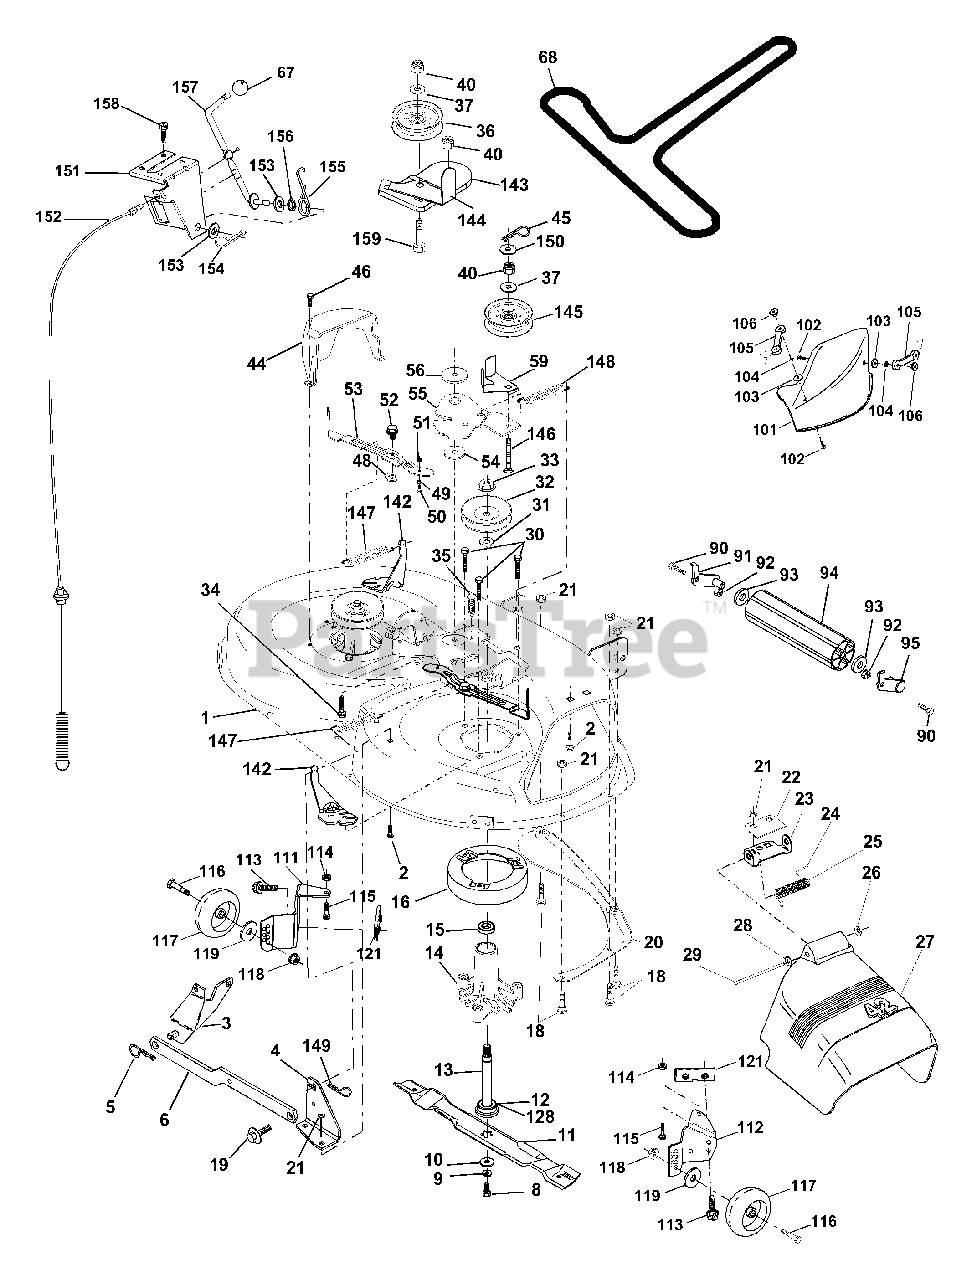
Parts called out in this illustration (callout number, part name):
1	Mower Deck Assembly, 42"
2	Bolt
3	Bracket Asm Fr. Sway Bar 3/42
4	Bracket Asm Deck 42" Sway Bar
5	Retainer Spring
6	Arm, Suspension, Rear
8	Bolt 3/8-24 x 25 Grade 8 patched
10	Washer,Hardened
11	Blade, Mulching 42"
11	Blade Mower 42" High Performance
12	Bearing, Ball #6204
13	Shaft Assembly, Mandrel, Vented
14	Housing, Mandrel, Vented
15	Bearing, Ball, Mandrel
16	Stripper, Vented Mower Deck
18	Bolt, Carriage 5/16-18 x 5/8
19	Bolt, Shoulder
20	Baffle, Vortex
21	Nut
22	Stiffener Bracket
23	Bracket, Deflector Mower 42"
24	Cap, Sleeve 80 x 112 Blk Mower
25	Spring, Torsion, Deflector 2 52
26	Nut, Push Phos & Oil
27	Shield, Deflector 42" Blk
28	Washer 11/32 x 5/8 x 16 Gauge
29	Rod, Hinge 42" 6 75 W/G
30	Screw Thdrol Washer Head
31	Washer, Spacer Mower Vented
32	Pulley, Mandrel
33	Nut, Toplock 9/16
34	Bolt
35	Fastener, Christmas Tree
36	Pulley, Idler, Flat
37	Washer 13/32 x 13/16 x 16 Gauge
40	Nut
44	Guard, Mandrel, LH
45	Retainer
46	Screw, Thdrol 1/4-20 x 5/8 T
48	Washer,Hardened
49	Roller Assembly, Cam Follower
50	Bolt, Shoulder #10-24 Grade 5
51	Locknut
52	Bolt, Shoulder 5/16-18 UNC
53	Arm Assembly, Pad, Brake
54	Washer,Hardened
55	Arm, Idler
56	Spacer, Retainer
59	Guard TUV Idler
67	Knob Round
68	V-Belt, 42" Mower
90	Bolt Fin Hex 3/8-16 UNC x 1
91	Bracket Asm Noseroller Lh
92	Nut, Lock, Hex W/Ins 3/8-16 UNC
93	Washer 17/32 x 7/8 x 16 Ga.
94	Roller Nose 38 & 42
95	Bracket Asm Noseroller Rh
101	Mulcher Cover
102	Screw
103	Washer, Flat
104	Washer, Lock
105	Latch Assembly
106	Nut, Weld
111	Bracket, Gauge, Wheel LH
112	Bracket, Gauge, Wheel RH
113	Screw 5/16 - 18 x 3/4
114	Nut, Keps 5/16 - 18 UNC
115	Bolt, Carriage 5/16-18 x 1/2
116	Bolt, Shoulder
117	Wheel, Gauge
118	Nut Centerlock 3/8-16
119	Washer 3/8 x 7/8 x 14 Ga.
121	Bracket, Extruded
128	Washer, Felt
142	Arm Spring Brake Mower
143	Bracket Arm Idler 42"
144	Keeper Belt 42" Clutch Cable
145	Pulley Idler Flat
146	Bolt Carriage Idler
147	Spring Extension
148	Spring Return Idler
149	Retainer Spring Yellow
150	Washer 9/32 x 3/4 x 16 Ga.
151	Bracket Clutch Cable
152	Clutch Cable 42"
153	Washer Flat 3/8" Type B
154	Spring Retainer
155	Spring Retention LVR CLTCH CAB
156	Spacer Clutch Cable
157	Rod Clutch Cable 3/8"
158	Screw Hex Thd Cut 1/4-20 x 5/8
159	Bolt Rdhd Sqn 3/8-16 UNC x 1-3/4
